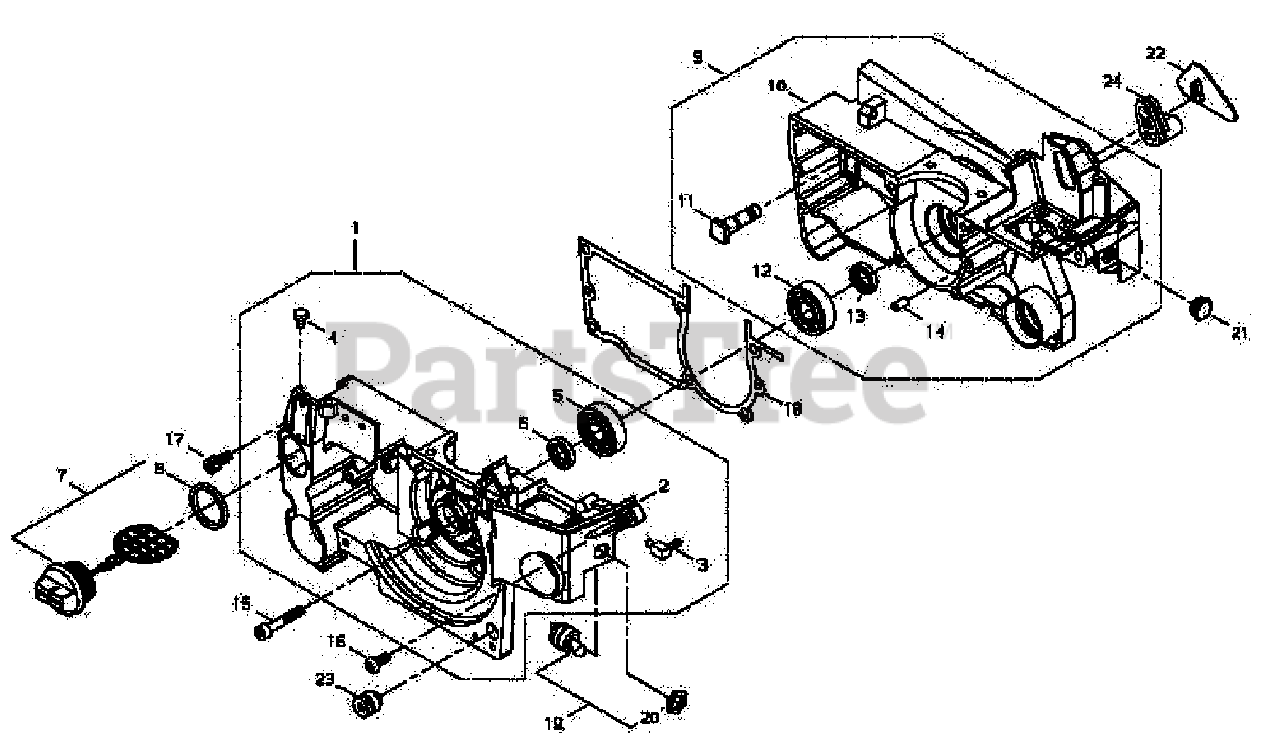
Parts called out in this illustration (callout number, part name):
1	CRANKCASE ASSY - LEFT
2	CRANKCASE - LEFT
3	CONNECTOR, PIPE
4	VALVE, CHECK
5	BEARING, BALL - 6201C3
6	SEAL, OIL - 12
7	CAP ASSY
8	GASKET, CAP
9	CRANKCASE ASSY - RIGHT
10	CRANKCASE - RIGHT
11	STUD, GUIDE BAR
12	BEARING, BALL - 6201C3
13	SEAL, OIL - 12
14	ROLLER
15	BOLT
16	SCREW
17	BOLT
18	GASKET, CRANKCASE
19	IGNITION SWITCH ASSY
20	NUT - 10
21	PLUG
22	STOPPER H
23	SUPPORTER
24	GROMMET
